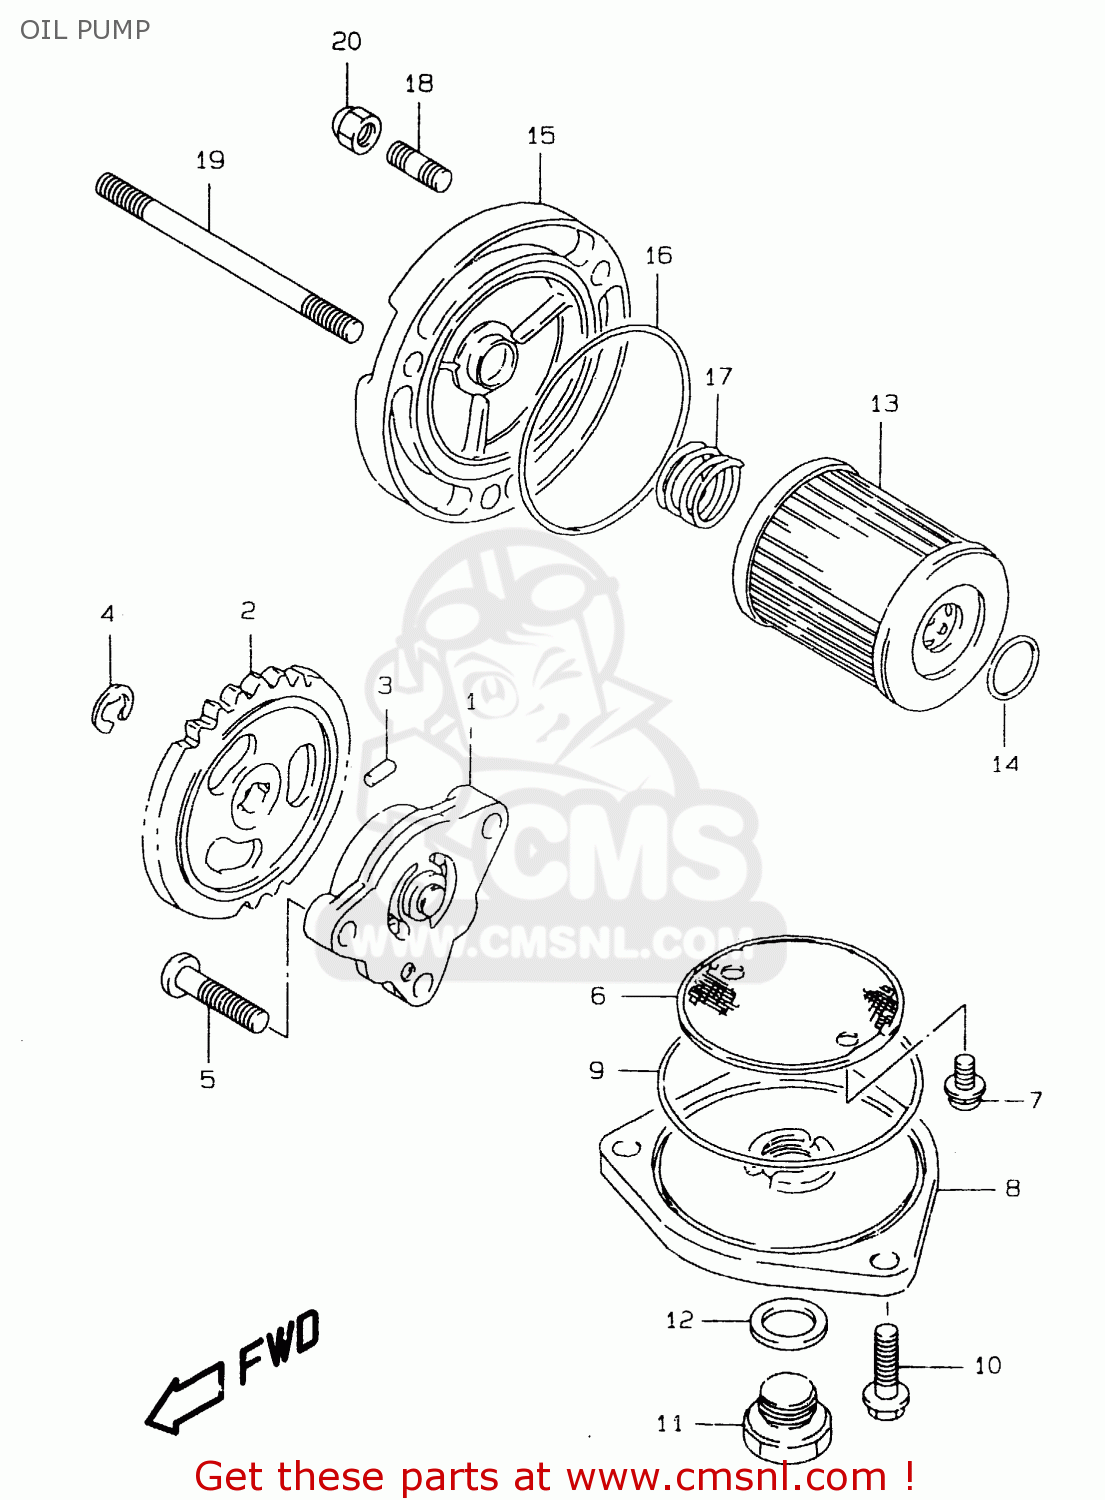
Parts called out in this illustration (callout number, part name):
1	PUMP ASSY,ENGINE OIL
2	GEAR,OIL PUMP DRIVEN (N
3	PIN(2.5X11.8)
4	E.RING
5	SCREW
6	STRAINER,ENGINE OIL
7	SCREW
8	CAP,OIL STRAINER
9	O RING(D:2.4,ID:60.5)
10	SCREW
11	PLUG
12	GASKET(14X19.2X2) (NAS)
13	FILTER ASSY,ENGINE OIL
14	O RING(D:1.9,ID:13)
15	CAP,OIL FILTER
16	O RING(D:2.4,ID:52.6)
17	SPRING
18	STUD 6X12
19	BOLT,STUD
20	NUT
